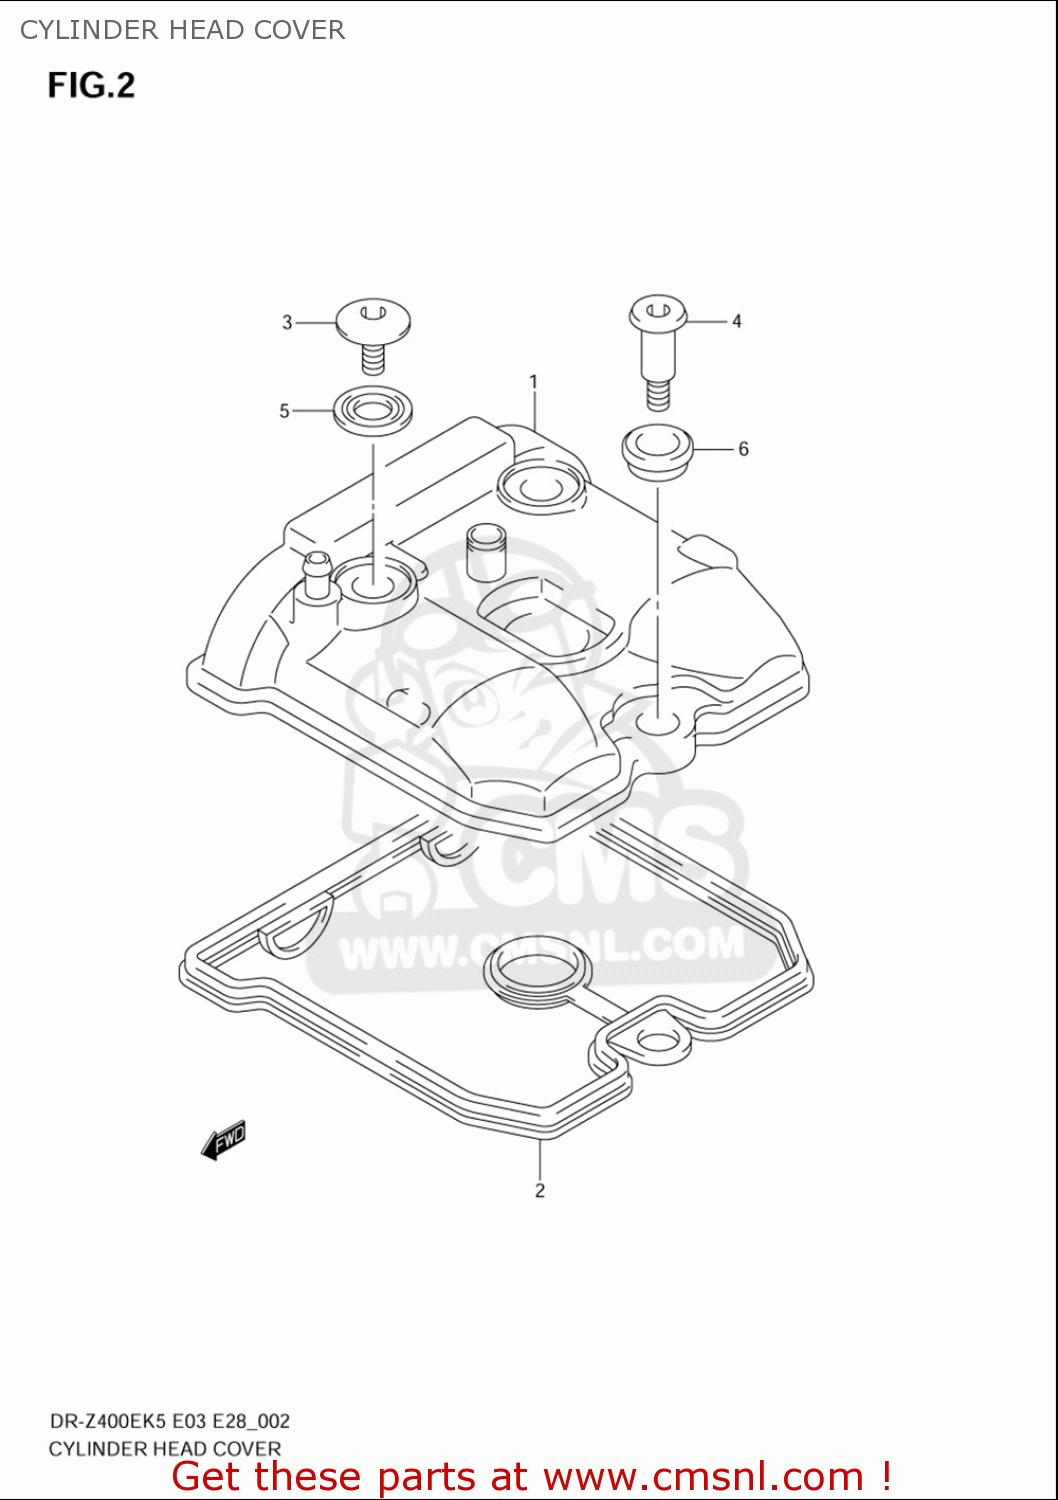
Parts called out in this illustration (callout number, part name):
1	COVER,CYLINDER HEAD
2	GASKET,CYL HEAD COVER (NAS)
3	BOLT(7X17.5)
4	BOLT(7X31)
5	WASHER(10.6X25.5X2.3)
6	CUSHION,HEAD COVER BOLT
